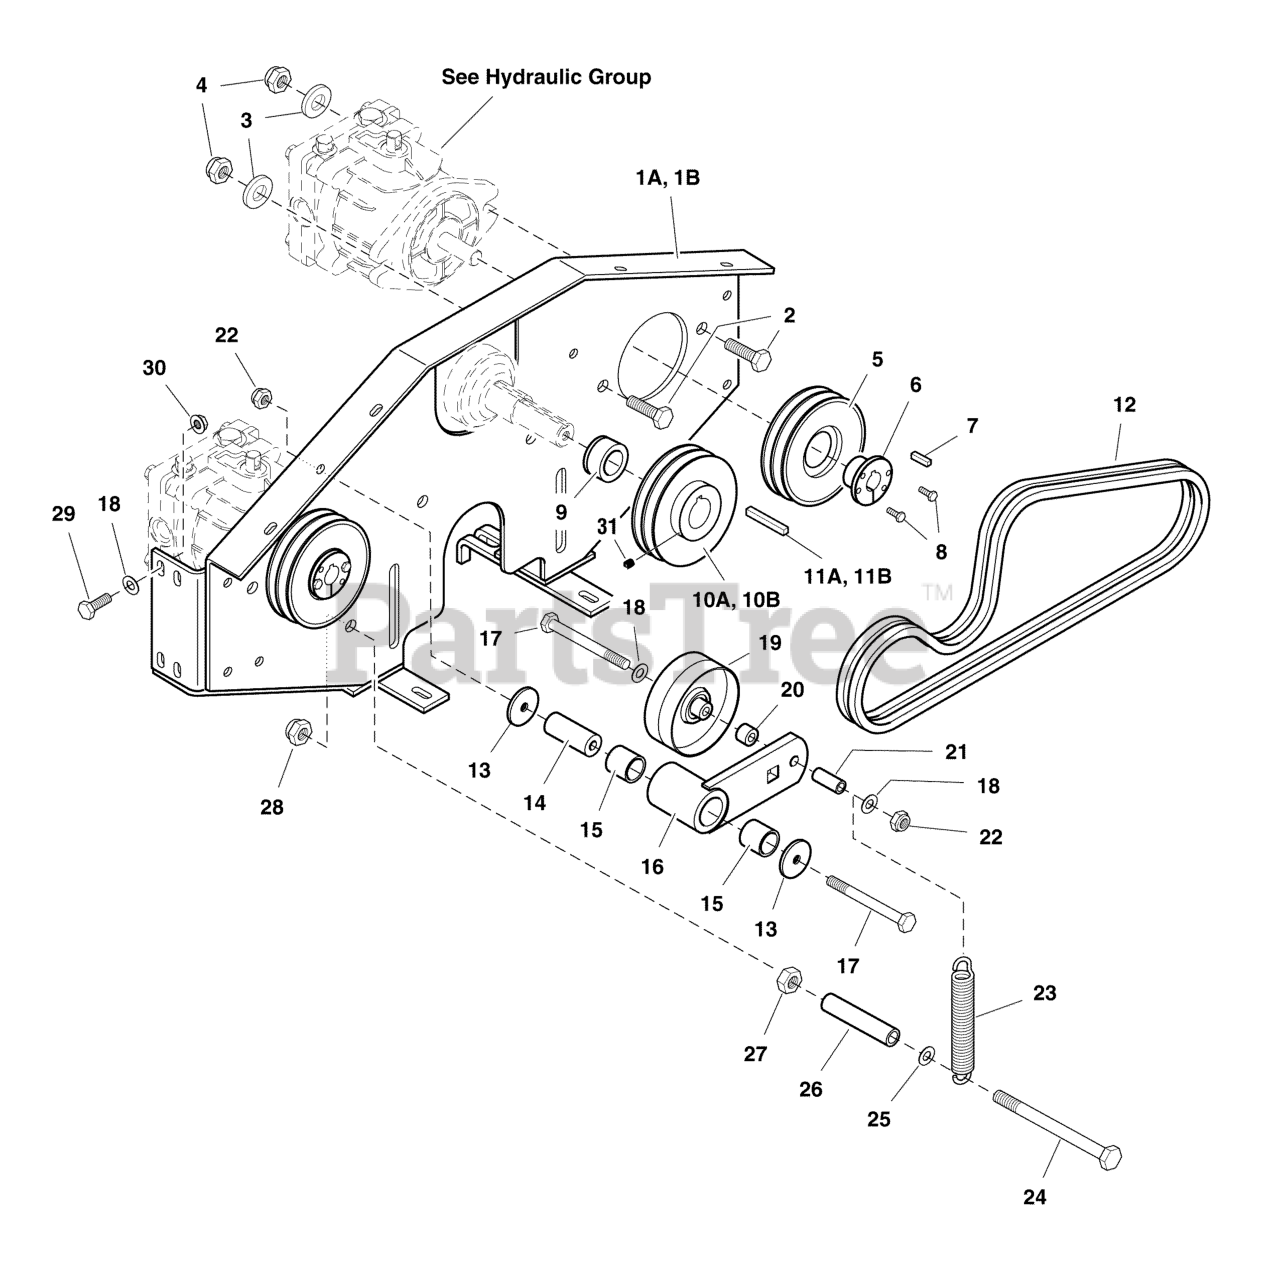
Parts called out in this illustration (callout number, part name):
1A	PUMP MOUNT PLATE
1B	PUMP MOUNT PLATE
2	BOLT, 1/2-20 X 1-3/4" GD8 CZ
3	WASHER, Frame Retaining
4	NUT, Hex, Nylon Lock, 1/2-20
5	PULLEY, Pump Drive
6	HUB, Taper Lock
7	KEY, 5MM SQ. x 25MM w/ Round Ends
8	BOLT, 1/4-20 X 1" GD5 CZ
9	SPACER, 1.13 x 1.75 x .75
10A	PULLEY, Crankshaft
10B	PULLEY, Crankshaft
11A	KEY, 5/16 SQ. X 1-1/2
11B	KEY, 1/4 SQ. x 3
12	BELT, Pump Drive (set of 2)
13	RETAINER, Idler Arm
14	SPACER, .39 X 1.00 X 2.55, SS
15	BUSHING, Brass
16	PUMP DRIVE IDLER ARM
17	BOLT, 3/8-16 X 4" GD5 CZ
18	WASHER, 3/8 SAE
19	PULLEY, Idler, Flat
20	SPACER, .39 x 1.00 x .25
21	SPACER, .38 x .50 x 1.00
22	NUT, 3/8-16 HEX NYLON LOCK
23	SPRING, Extension
24	BOLT, 1/2-13 x 5
25	WASHER, 1/2 SAE
26	HOSE, 3-1/4
27	NUT, 1/2-13 Hex Jam
28	NUT, 1/2-13 HEX NYLON LOCK
29	BOLT, 3/8-16 X 1" GD5 CZ
30	NUT, 3/8-16 Hex Serrated Flange
31	SET SCREW, 5/16-18 X 3/8, KNURL, W/PATCH
